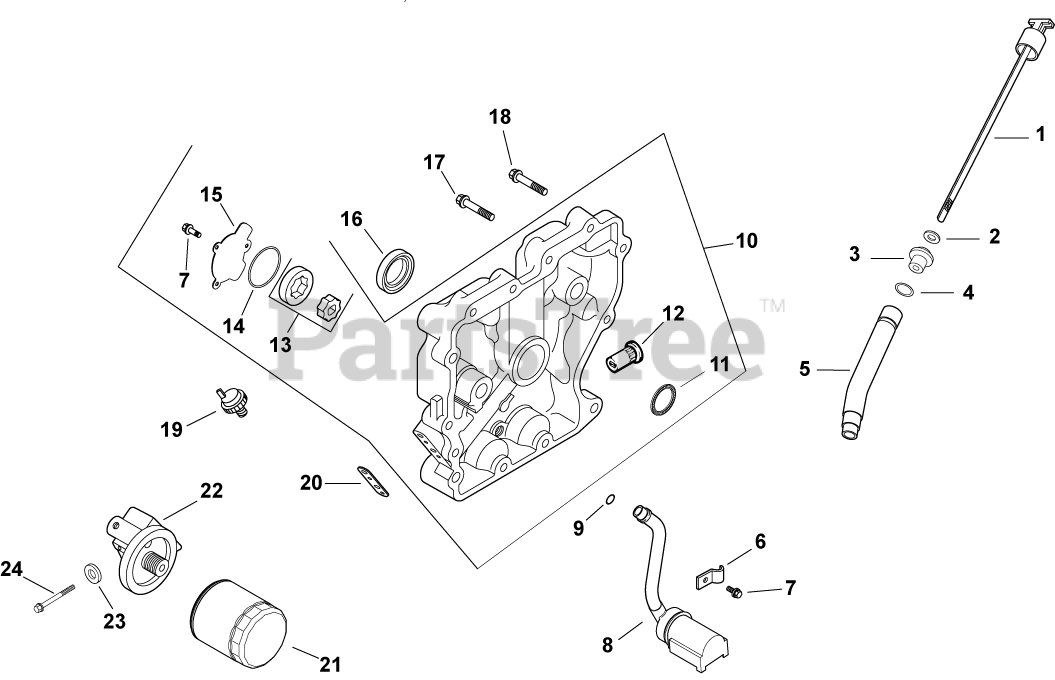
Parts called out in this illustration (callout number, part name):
3	SEAL USE 25 032 13-S
5	TUBE, OIL FILL
7	SCREW,FLG THD FRM M5X0.8X16-(#25086398S)
8	KIT, OIL PICK-UP
9	O-RING (.5" DIA)
10	CLOSURE PLATE ASSEMBLY
11	BEARING, CRANKSHAFT
12	VALVE, OIL PRESSURE RELIEF
13	PUMP ASSEMBLY, OIL
14	O-RING (1.78" DIA)
15	COVER, OIL PUMP
16	SEAL, OIL
17	SCREW, HEX FLANGE -USE 24 086 17-S
18	SCREW, FLG M8X1.25X45
19	SENSOR, OIL PSI
20	GASKET, OIL FILTER ADAPTER
21	OIL FILTER
22	ADAPTER - DISCONTINUED
24	SCREW, FLG M6X1.0X60
